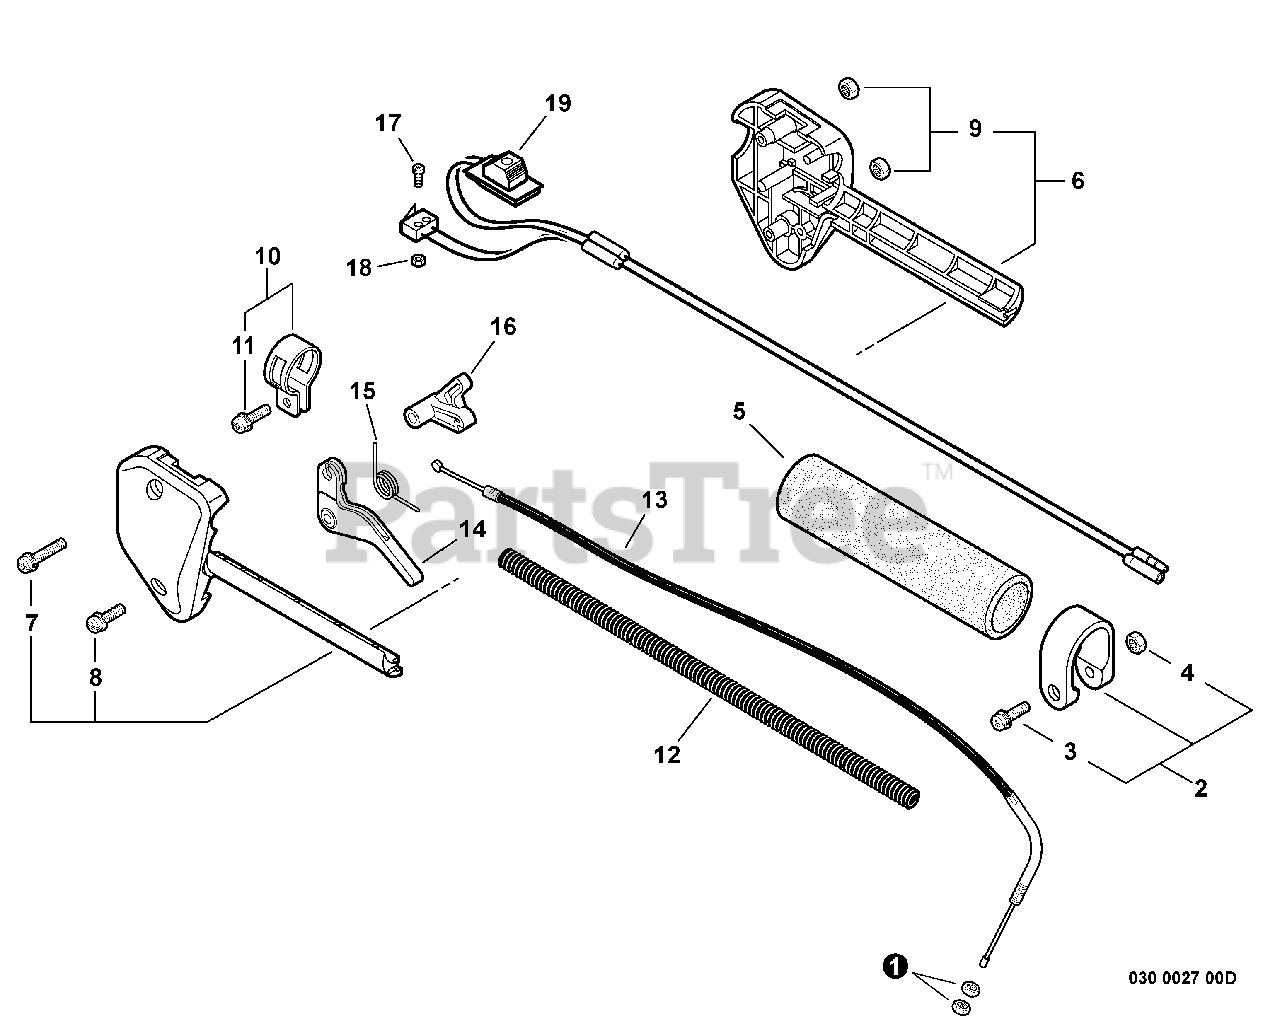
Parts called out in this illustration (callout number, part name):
2	CLAMP KIT
3	SCREW - 5X28
5	GRIP, HANDLE
6	CONTROL HANDLE KIT
7	SCREW - 5X35
8	SCREW - 5X25
10	CLAMP KIT
11	SCREW - 5X14
12	TUBE, PROTECTIVE - CORRUGATED
13	CABLE, THROTTLE
14	TRIGGER, THROTTLE
15	SPRING, TRIGGER
16	LOCKOUT, THROTTLE
17	SCREW - 2X10
19	IGNITION SWITCH ASSY
